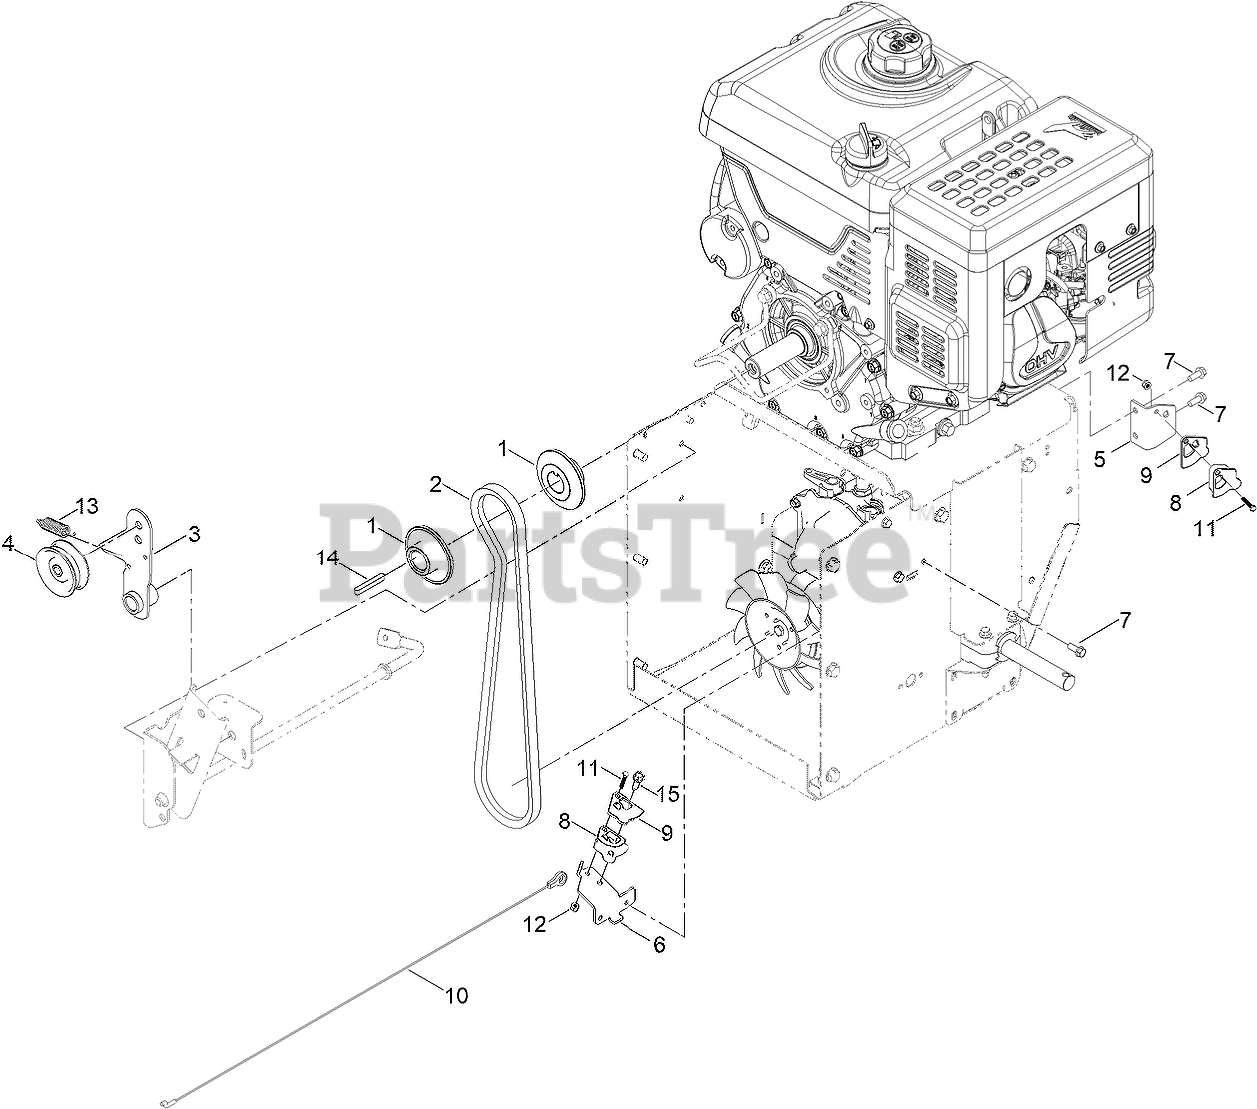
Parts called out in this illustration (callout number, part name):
1	SHEAVE-TRACTION
2	BELT-TRACTION (A, 41.00)
3	ARM-IDLER, TRACTION
4	PULLEY-IDLER
5	BRACKET-CABLE
6	ANCHOR-CABLE
7	SCREW-HWH
8	GUIDE-CABLE
9	CAP-GUIDE, CABLE
10	CABLE-TRACTION
11	Screw, Machine, Nozzle, 8-32 x 7/8"
12	NUT-HEX, NYLOCK
13	SPRING-EXTENSION
14	KEY-SQUARE
15	SCREW-HWHTF
